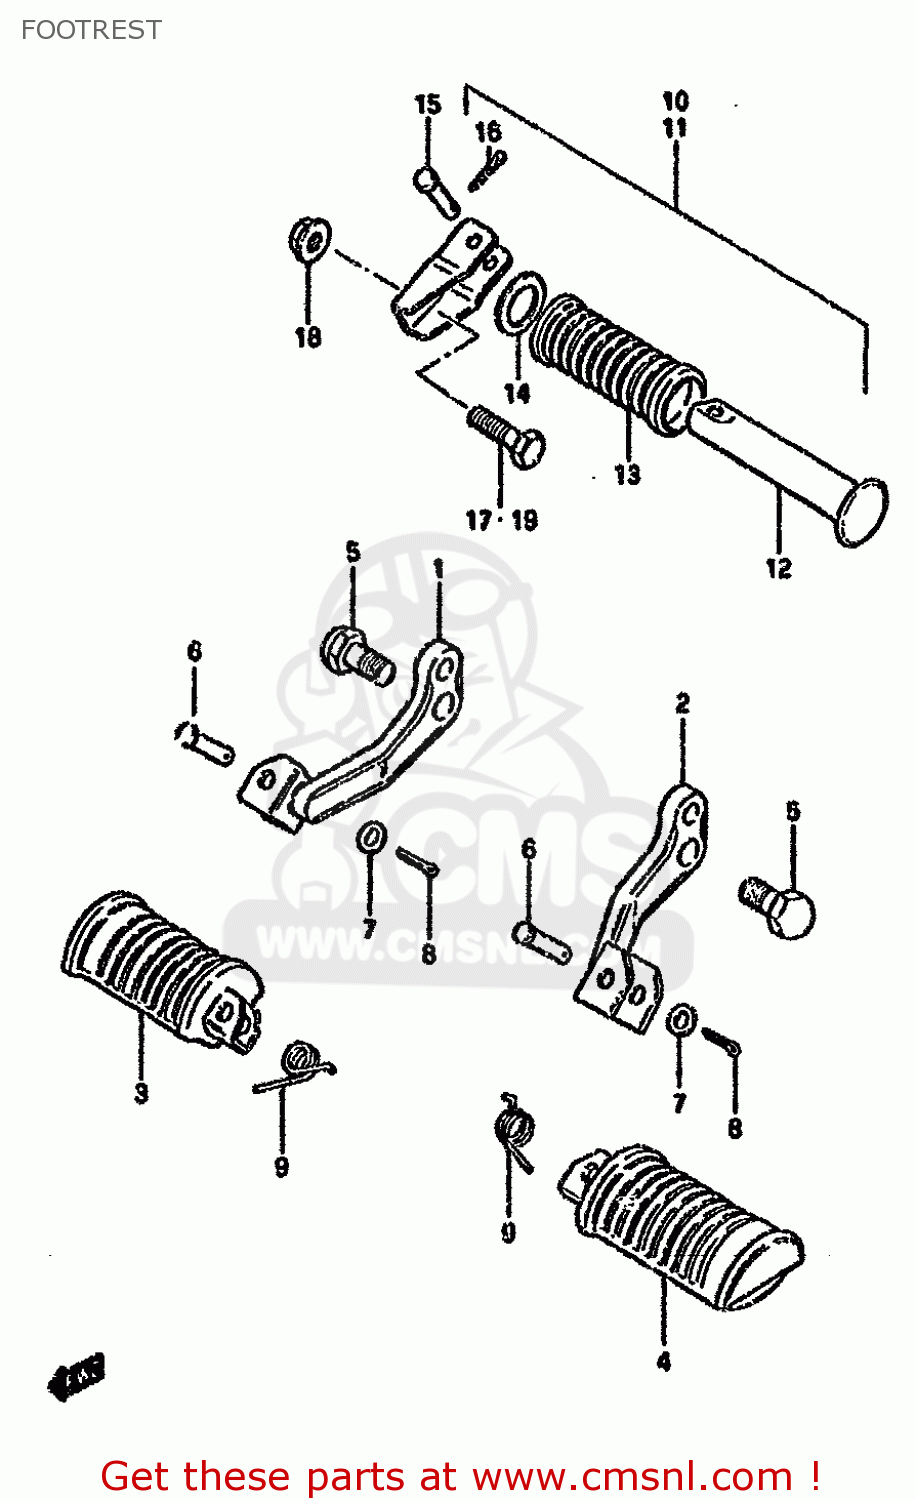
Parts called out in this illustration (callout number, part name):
1	HOLDER,FR FOOTREST,R
2	HOLDER,FR FOOTREST,L
3	RUBBER,PILLION FOOTREST,R
4	RUBBER,PILLION FOOTREST,L
5	BOLT
6	PIN
7	WASHER
8	PIN 20X20
9	SPRING
10	FOOTREST ASSY,PILLION,R
11	FOOTREST ASSY,PILLION,L
12	BAR,FOOTREST RUBBER
13	RUBBER,PILLION FOOTREST
14	WASHER (19.5X32X2)
15	PIN
16	PIN
17	BOLT
18	NUT
19	BOLT
